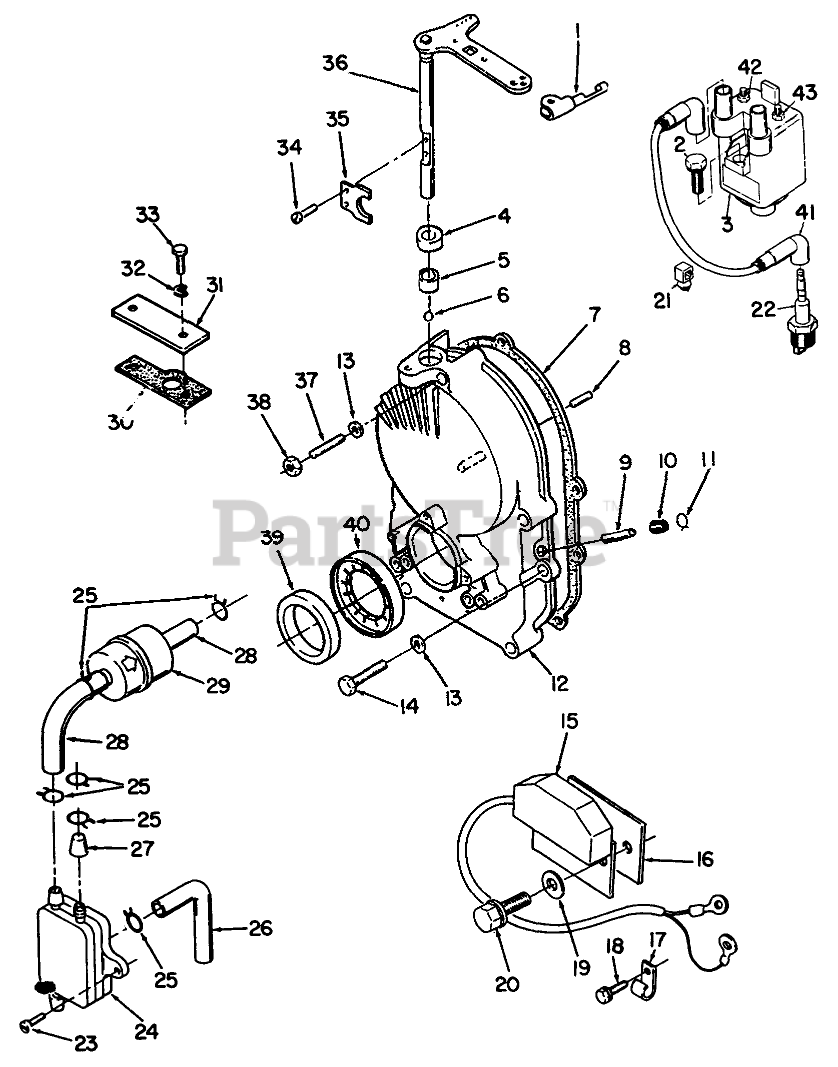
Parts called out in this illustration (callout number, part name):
2	SCREW-HH
3	COIL-BATTERY IGNITION
5	BEARING
7	GEAR CASE MTG GASKET
8	PIN-DOWEL
9	TUBE-PORT, VACUUM
10	CAP-FUEL OUTLET
11	CLAMP
12	Gearcase Kit (Includes Ref. #4-6, 8-11, 26, & 34-36)
13	WASHER
14	SCREW-HH
15	CONTROL-IGNITION
16	INSULATOR-IGN MODULE
17	CLIP-WIRE
18	SCREW-HH
19	WASHER-LOCK, INT
20	SCREW-HH
21	WIRE ROUTING CLIP
22	SPARK PLUG
23	SCREW-TAPPING PAN HD
24	PUMP-FUEL
25	CLAMP
26	Line-Pulse
27	CAP-FUEL OUTLET
28	Hose
29	FILTER-FUEL
30	GASKET
31	PLATE-COVER
32	WASHER-FLAT
33	SCREW-HH
34	Screw
36	SHAFT/ARM-GOVERNOR
37	STUD-GEAR COVER
38	NUT-HEX
39	Seal-Oil
40	ROTOR-IGNITION
41	Cable Plug 9" Long
42	NUT-HEX FLANGE
43	NUT-HEX FLANGE
